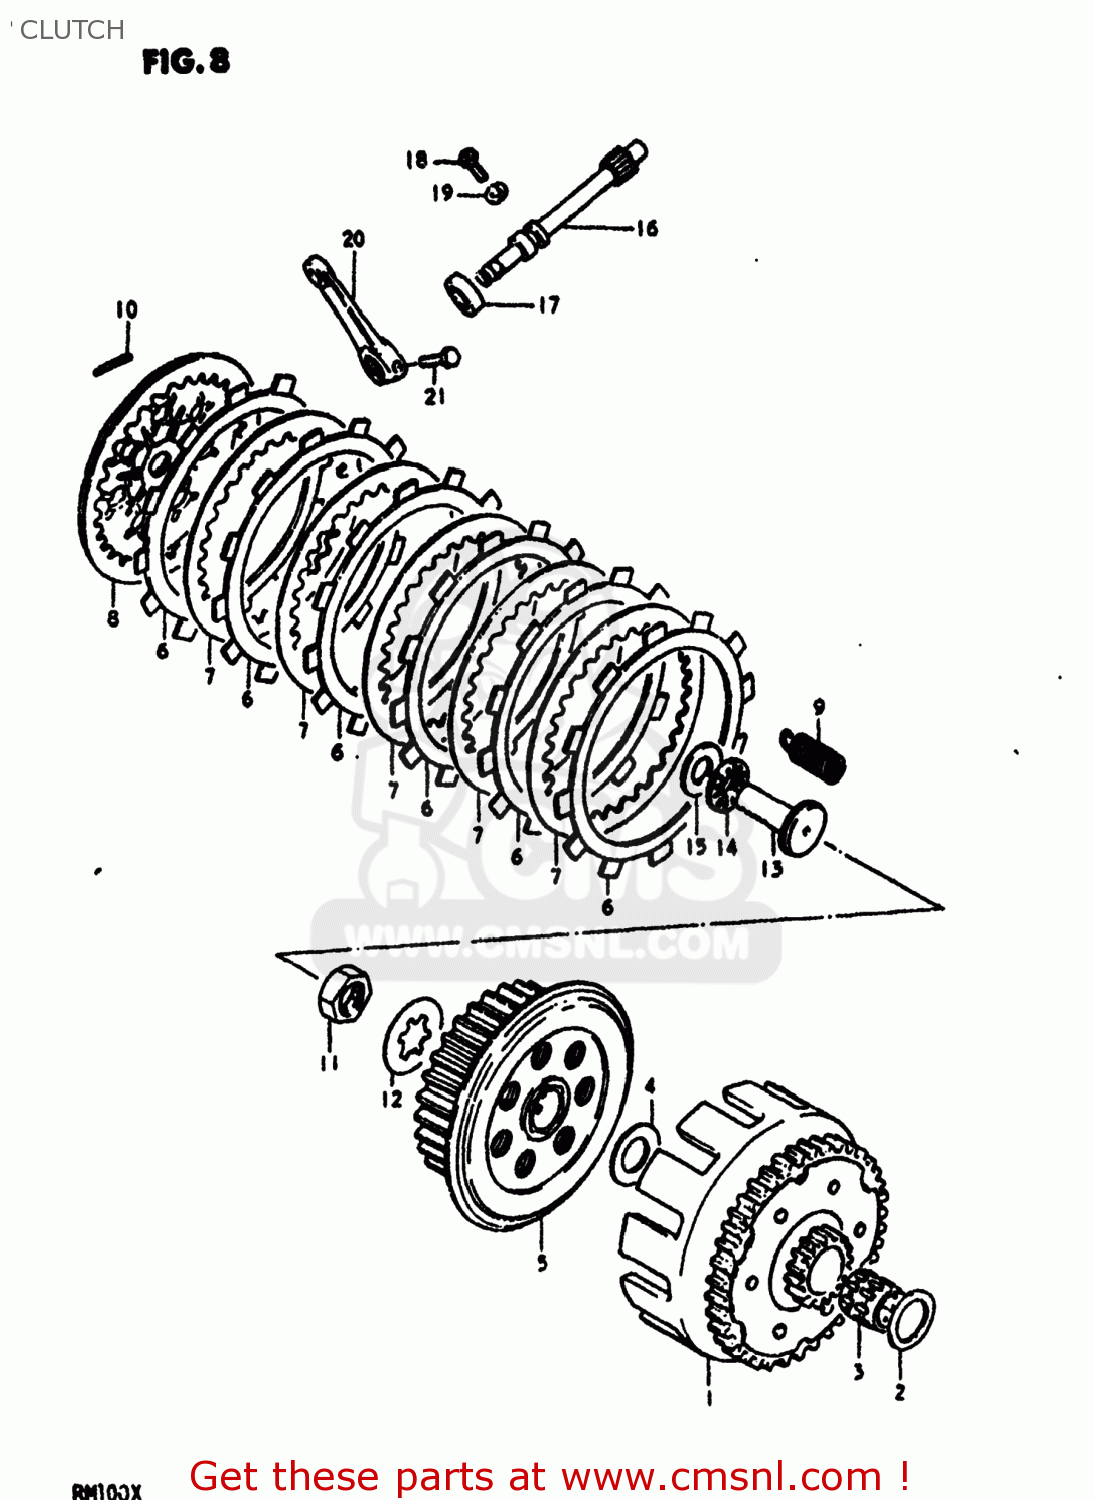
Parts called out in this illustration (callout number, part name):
1	GEAR ASSEMBLY,PRIMARY DRIVE
2	WASHER
3	BEARING(20X25X26)
4	WASHER
5	HUB,CLUTCH SLEEVE
6	PLATE,CLUTCH DRIVE
7	PLATE,CLUTCH DRIVEN
8	PLATE,CLUTCH PRESSURE
9	SPRING
10	PIN(2.5X19.8)
11	NUT
12	WASHER,LOCK
13	RACK,CLUTCH RELEASE
14	BEARING(10X22X2.8)
15	WASHER
16	PINION,CLUTCH RELEASE
17	SEAL,OIL (10X17X5)
18	BOLT(6X12)
19	WASHER
20	ARM,CLUTCH RELEASE
21	BOLT, UPPER
